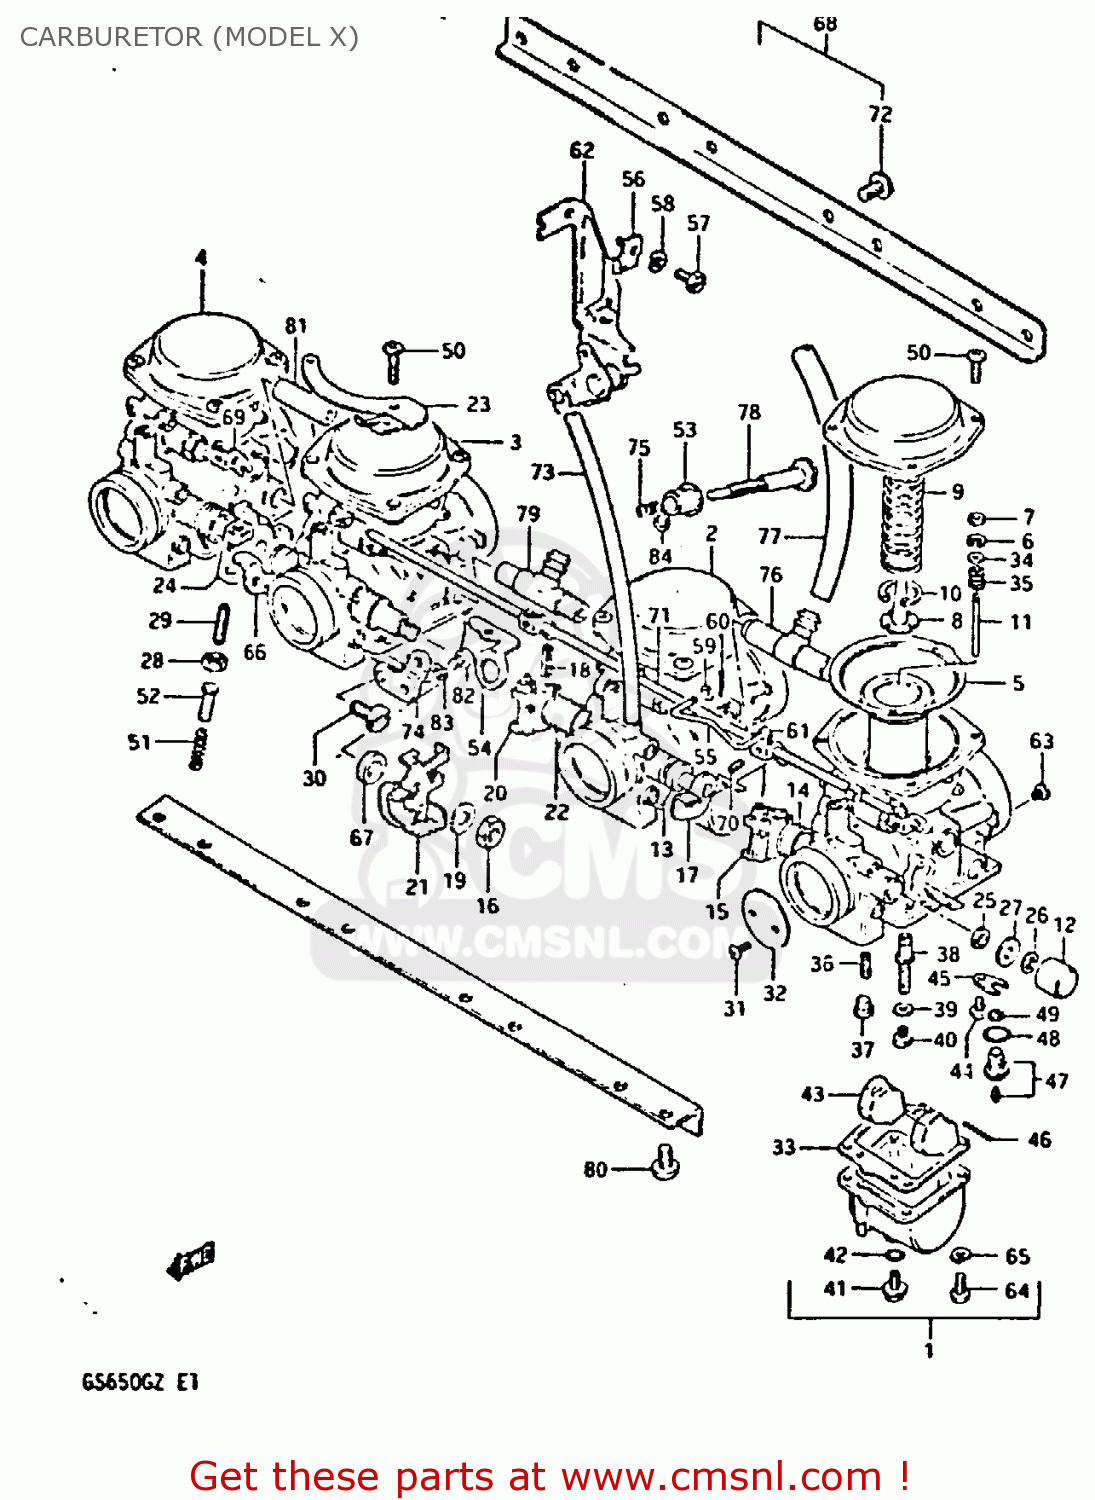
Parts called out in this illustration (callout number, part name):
1	CARBURETOR ASSY, LH
2	CARBURETOR ASSY, ML
3	CARBURETOR ASSY, MR
4	CARBURETOR ASSY, RH
5	DIAPHRAGM
6	CLIP,NEEDLE
7	RING
8	HOLDER,GUIDE
9	SPRING
10	E RING
11	NEEDLE, JET (5C47-3)
12	CAP
13	GASKET,THROTTLE SHAFT (NAS)
14	SPRING,THROTTLE SHAFT
15	SHAFT,THROTTLE
16	NUT 8MM
17	SHAFT,THROTTLE
18	PIN,THROTTLE SHAFT
19	WASHER
20	LEVER,THROTTLE SHAFT
21	LEVER ASSEMBLY,THROTTLE
22	SPRING,THROTTLE SHAFT
23	BRACKET
24	SHAFT,THROTTLE
25	SEAL
26	E RING
27	GASKET,THROTTLE SHAFT (NAS)
28	NUT
29	SCREW
30	SCREW
31	SCREW
32	VALVE,THROTTLE
33	GASKET,FLOAT CHAMBER (NAS)
34	WASHER
35	SPRING
36	JET, PILOT (42.5)
37	PLUG,NEEDLE JET
38	JET, NEEDLE (Y-7)
39	WASHER,NEEDLE NOZZLE
40	JET, MAIN
41	PLUG,DRAIN
42	GASKET (NAS)
43	FLOAT
44	SCREW 4X6
45	PLATE,NEEDLE VALVE FITING
46	PIN,FLOAT
47	VALVE ASSEMBLY,NEEDLE
48	O-RING,NEEDLE VALVE
49	FILTER
50	SCREW
51	SPRING,THROTTLE SCREW
52	PIN,THROTTLE LEVER
53	BUSH
54	BRACKET,THROTTLE ADJUST
55	ROD,STARTER LEVER
56	BRACKET,STARTER
57	BOLT
58	LOCK WASHER
59	SEAT,SPRING
60	PIN
61	LEVER ASSY
62	BRACKET
63	JET,AIR(140)
64	SCREW
65	LOCK WASHER
66	SHAFT,THROTTLE
67	WASHER
68	CARBURETOR ASSEMBLY
69	LEVER
70	SCREW
71	SHAFT,STARTER
72	SCREW
73	HOSE
74	BRACKET,THROTTLE ADJUST
75	SPRING
76	NIPPLE
77	HOSE
78	SCREW
79	NIPPLE,CARBURETOR
80	SCREW 6X12
81	NIPPLE
82	SCREW
83	LOCK WASHER
84	WASHER
